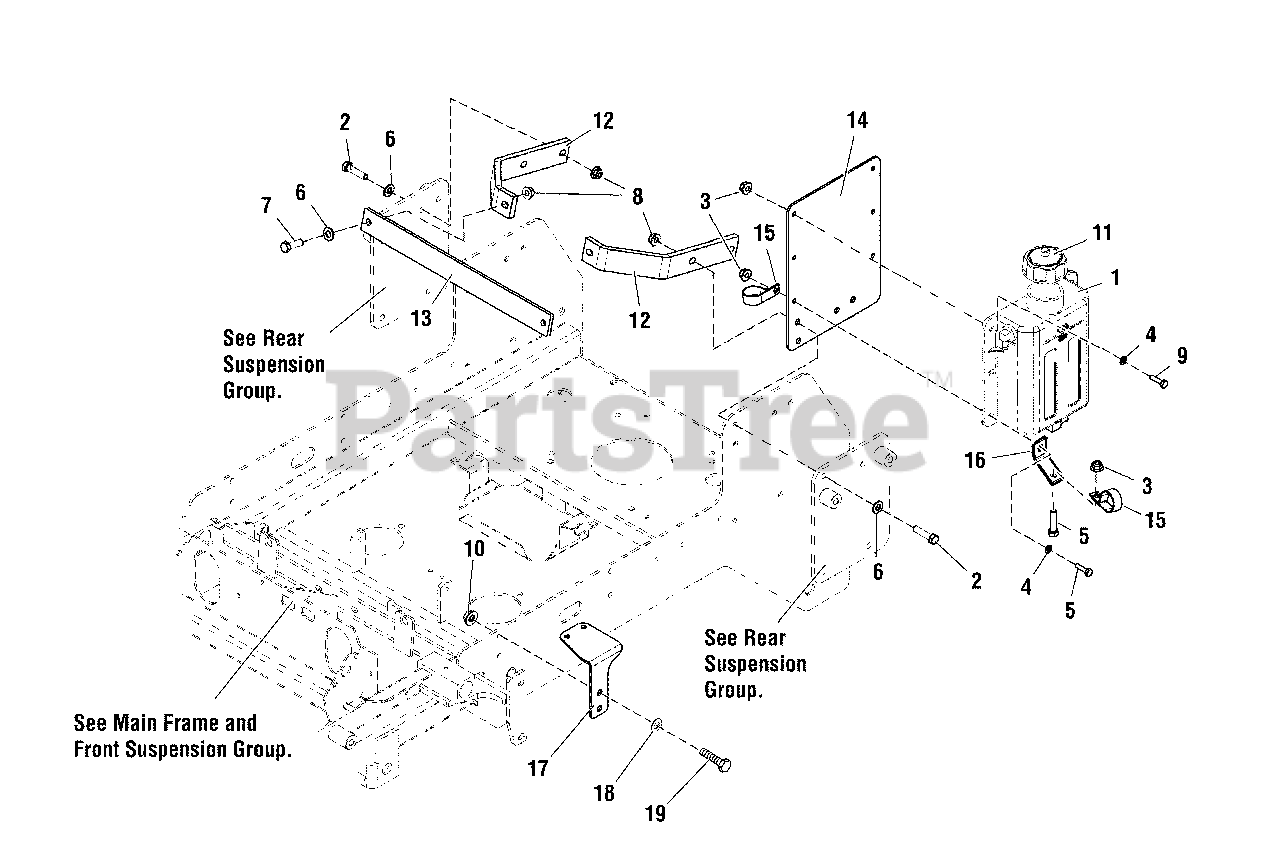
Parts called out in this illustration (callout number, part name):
1	TANK, HYDRAULIC, ASSEMBLY (See Hydraulic Group)
2	BOLT, 3/8-16 X 1-1/2 GD5 YZ
3	NUT, 1/4-20 HEX NYLOCK FLANGE (5025391)
4	WASHER, 1/4 SAE (5025154)
5	BOLT, 1/4-20 X 1" GD5 CZ
6	WASHER, 3/8 SAE
7	BOLT, 3/8-16 X 1-1/4 GD5
8	NUT, 3/8-16 HEX NYLOCK FLANGE
9	BOLT, 1/4-20 X 3/4 GD5 YZ
10	NUT, 5/16-18 HEX NYLOCK FLANGE
11	CAP, HYDRAULIC (See Hydraulic Group)
12	BAR, STABILIZER, SIDE
13	BAR, STABILIZERS, CENTER
14	PLATE, HYDRAULIC TANK MOUNT
15	CLAMP, VINYL INSULATED
16	BRACKET, HOSE - BLK
17	MOUNT, OIL FILTER - BLK
18	WASHER, 5/16" SAE
19	BOLT, 5/16-18 X 1 GD5 YZ
